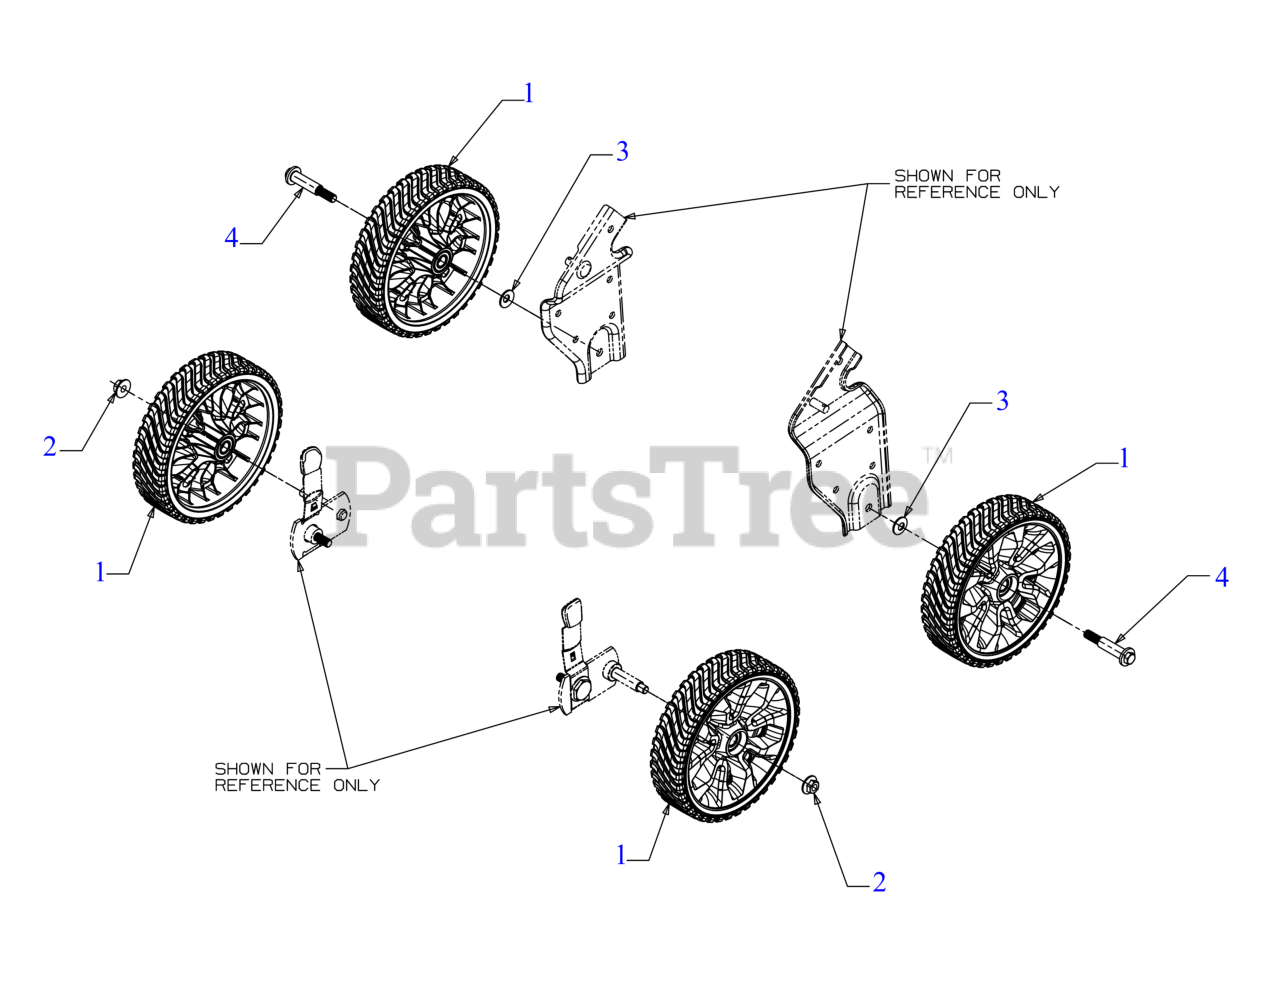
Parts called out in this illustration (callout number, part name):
1	WHEEL ASSEMBLY 8 x 2 GRAY BB
2	FLANGE LOCK NUT
3	BELL WASHER .400 ID x .88 x .060
4	SHOULDER SCREW .496X1.605 3/8-16
